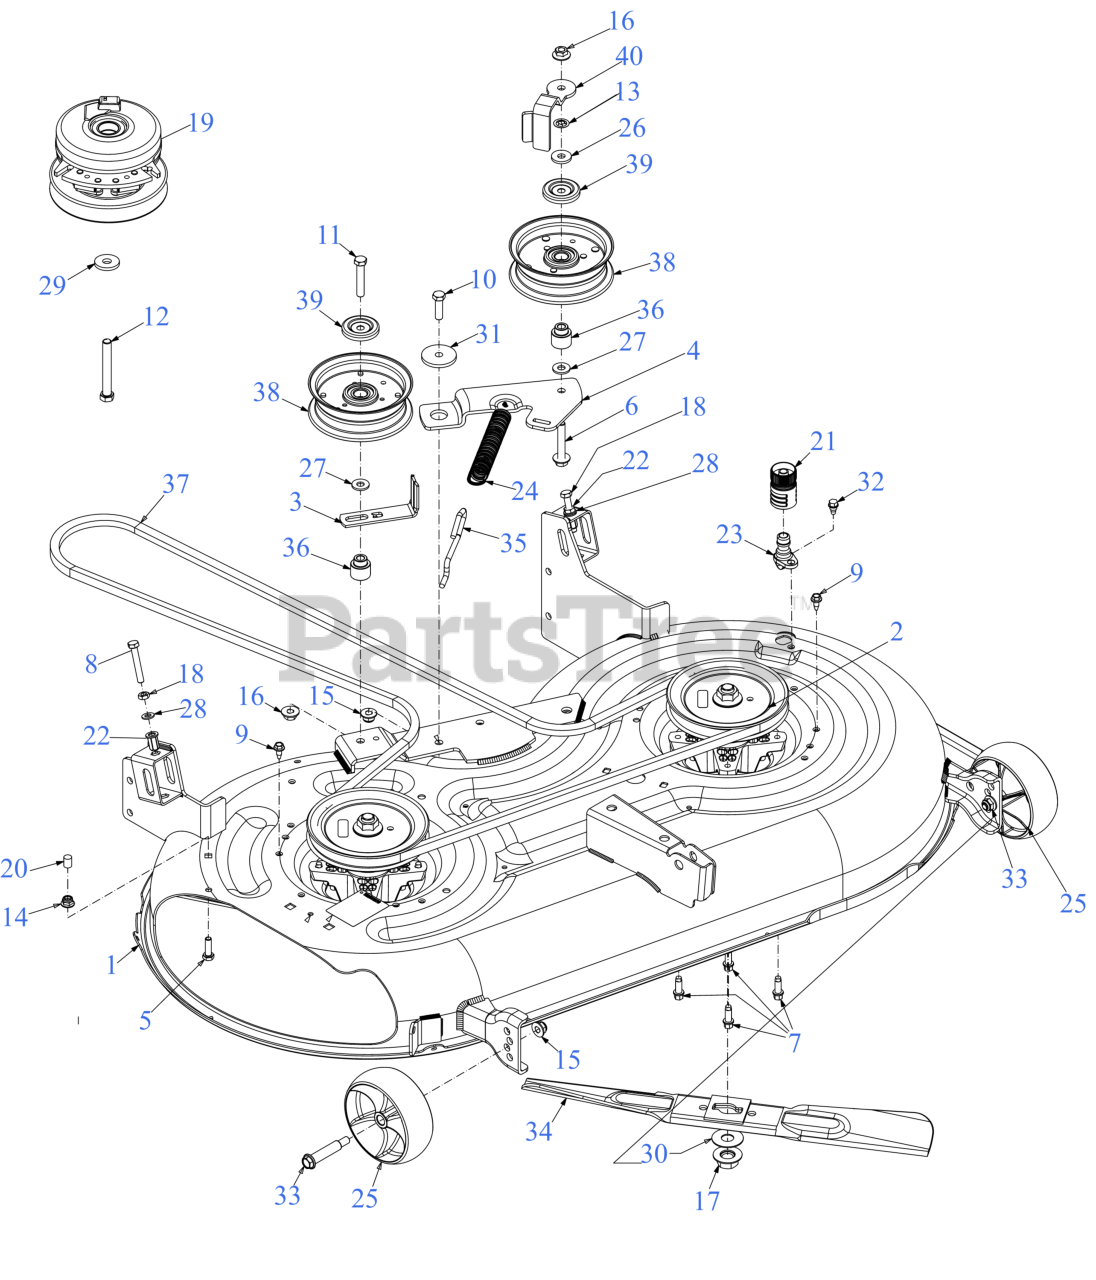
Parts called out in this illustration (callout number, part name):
1	42" DECK SHELL
2	SPINDLE ASSEMBLY (6.3 DIA)
4	42" IDLER PIVOT BRACKET
5	SCREW 5/16-18 x 1.0 GR5
6	SCREW 3/8-16 x 2.25 GR5
7	SCREW 5/16-18 x .875
8	SCREW-FULL THREAD 5/16-18 GR5
9	SCREW 1/4-20X.625
10	SCREW 3/8-16 x 1.25 GR5
11	SCREW 3/8-16 x 2.0 GR5
12	SCREW 7/16-20 x 3.25 GR5
14	FLANGE LOCK NUT 5/16-18
16	FLANGE LOCK NUT
17	FLANGE NUT 5/8-18
19	ELECTRIC PTO CLUTCH
21	WATER NOZZLE ADAPTER
22	NUT RIVET 5/16-18
23	DECK WASH NOZZLE
24	EXTENSION SPRING .94 x 6.75 RZT
25	DECK WHEEL (5.0 DIA x 1.875)
25	Cub Cadet 5" DECK WHEEL (06305A) (W/BOLT)
26	FLAT WASHER .385 x 1.00 x .135
27	FLAT WASHER .385X.870X.090
28	FLAT WASHER
29	FLAT WASHER .445 x 1.248 x .170
30	FLAT WASHER .635X1.585X.062 HDN
31	SHOULDER SPACER
32	SHOULDER SCREW 1/4-20 x .50
33	SHOULDER BOLT (.50 X 2.0 x 3/8 -16)
34	21.23" BLADE (2IN1) (S SHAPE CENTER HOLE)
34	21.23" XTREME BLADE (2IN1) (S SHAPE CENTER HOLE)
34	21.23" LOW LIFT BLADE (S SHAPE CENTER HOLE)
35	DECK SPRING HOOK
36	SHOULDER SPACER
37	V-BELT A SEC x 117.0
37	Cub Cadet 42" RZT DECK BELT
37	Troy-Bilt 42" RZT DECK BELT
38	IDLER PULLEY 4.50" DIA
39	IDLER PULLEY CAP
40	BELT KEEPER
